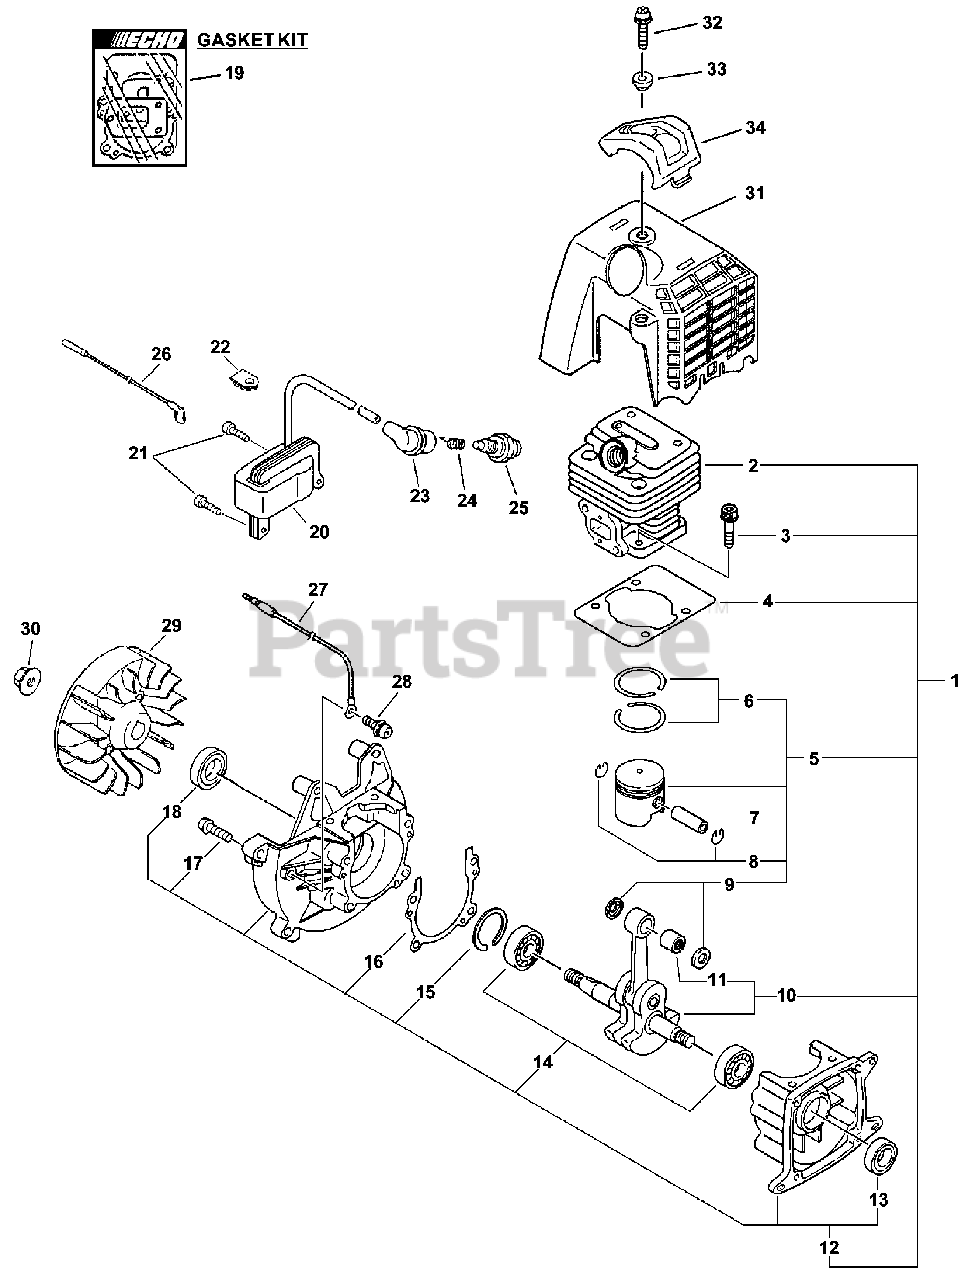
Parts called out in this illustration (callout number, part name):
1	SHORT BLOCK -- SB1045
2	CYLINDER
3	SCREW - 5X22
4	GASKET, CYLINDER
5	PISTON KIT
6	RING, PISTON
7	PIN, PISTON
8	RING, RETAINING
9	SPACER, PISTON
10	CRANKSHAFT ASSY
11	BEARING, NEEDLE - 8
12	CRANKCASE KIT
13	SEAL, OIL
14	BEARING, BALL - 6001C3
15	RING, RETAINING - 28
16	GASKET, CRANKCASE
17	SCREW - 5X25
18	SEAL, OIL - 12
19	GASKET KIT
20	COIL, IGNITION
21	SCREW - 5X16
23	CAP, SPARK PLUG
24	TERMINAL, SPARK PLUG CAP
25	SPARK PLUG -- BPM-7Y
26	LEAD - IGNITION
27	LEAD - GROUND
28	SCREW - 5X10
29	FLYWHEEL
30	NUT - 8 -- FLANGE
31	COVER, ENGINE - GRAY
32	SCREW - 5X16
33	COLLAR - 5
34	GUARD - TOP
